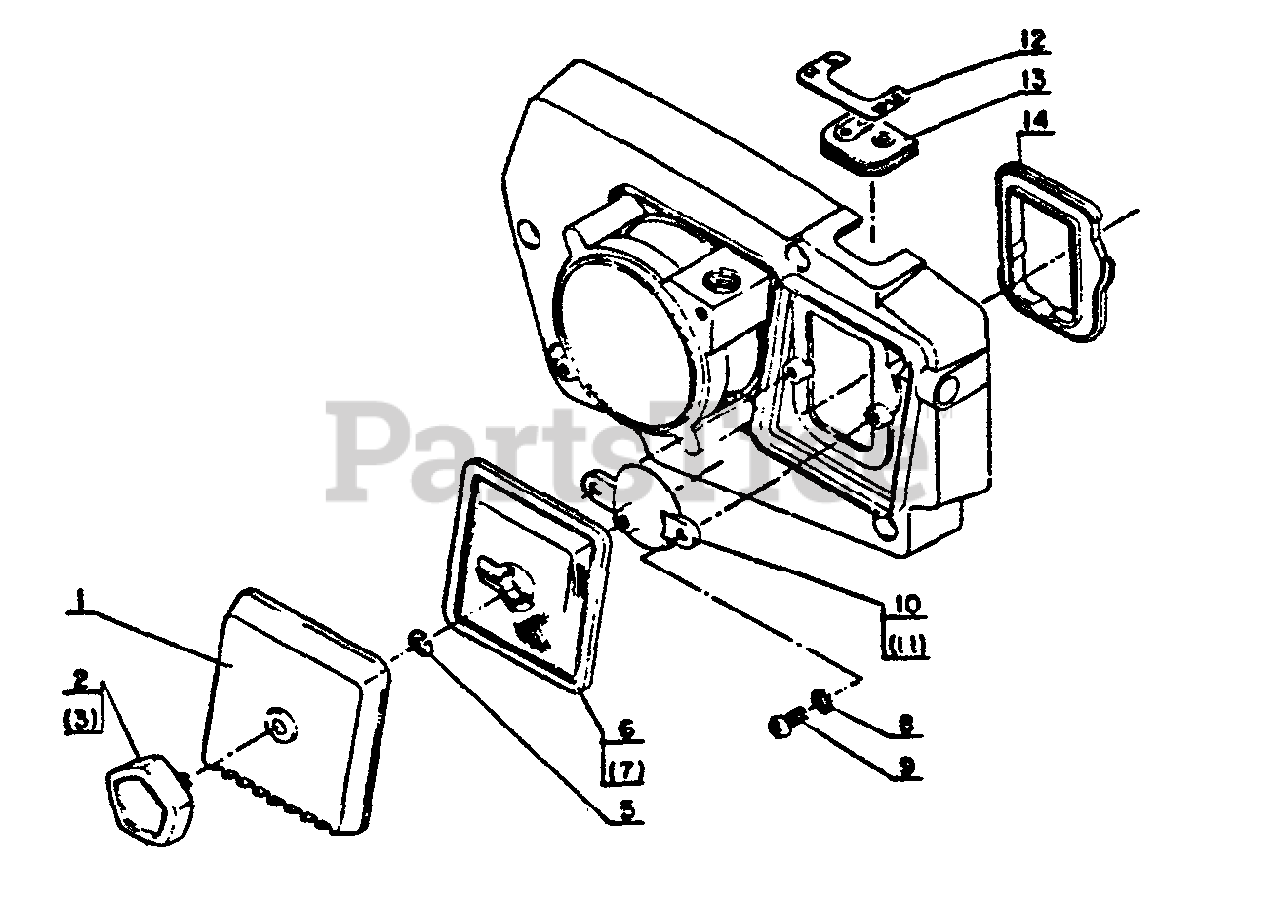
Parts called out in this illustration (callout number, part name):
1	COVER, AIR FILTER
2	WINGNUT
5	E-RING 4
6	FILTER, AIR
8	WASHER, SPRING 4 MM
9	SCREW 4×8
10	PLATE, PREVENT
12	LABEL - FUEL
13	GROMMET
14	PACKING
